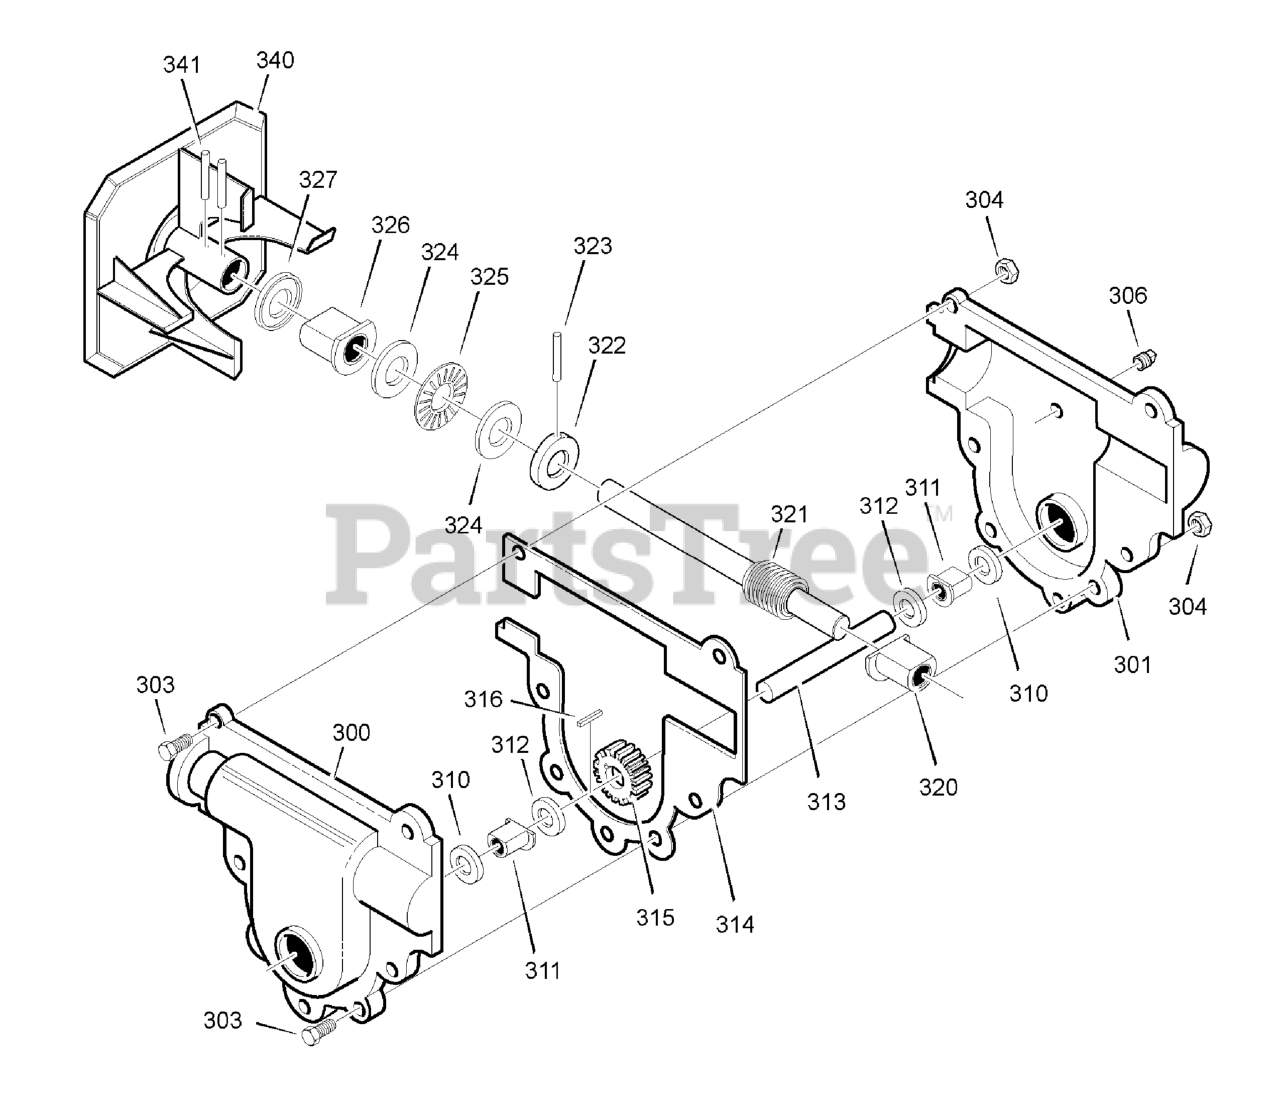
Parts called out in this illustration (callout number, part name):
300	CASE, GEAR, RH
301	CASE, GEAR, LH
303	SCREW, 1/4-20 X 0.75
304	NUT,1/4-20
306	SCREW, 3/8-16 X 0.50
310	SEAL, OIL
311	BEARING, FLANGE
312	WASHER, FLAT
313	SHAFT, AUGER OUTPUT
314	GASKET, GEAR BOX
315	GEAR, WORM
316	KEY, WOODRUFF #61
320	BEARING, FLANGE
321	SHAFT, AUGER INPUT (IMPELLER)
322	COLLAR, THRUST
323	PIN, SPRING
324	WASHER, FLAT
325	BEARING, ROLL
326	BEARING, FLANGE
327	SEAL, OIL
341	PIN, SPRING
